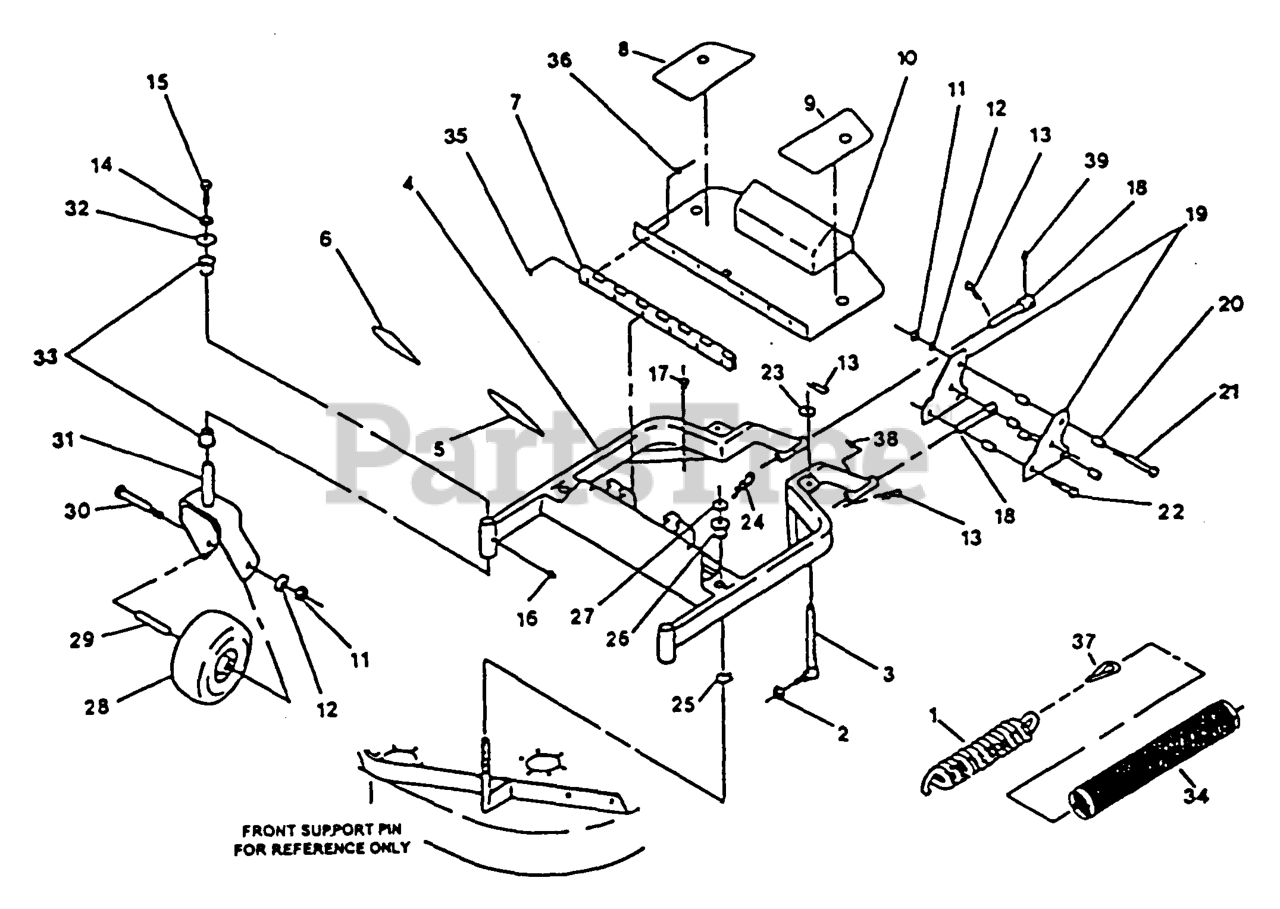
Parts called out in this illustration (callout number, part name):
5	PAD,ANTI SKID UPPER LH
6	PAD,ANTI SKID UPPER RH
7	HINGE,FLOORPAN
8	PAD,ANTI SKID LOWER RH
13	PIN,HAIR COTTER
18	PIVOT MOUNT W/ZERK PLTD
19	BRACKET,DECK PIVOT PLTD
23	SPACER,REAR DK SUPP PLTD
26	BUSHING-DECK
27	SPACER-CASTER
33	BEARING-FLANGED
34	COVER,DECK SPRING
